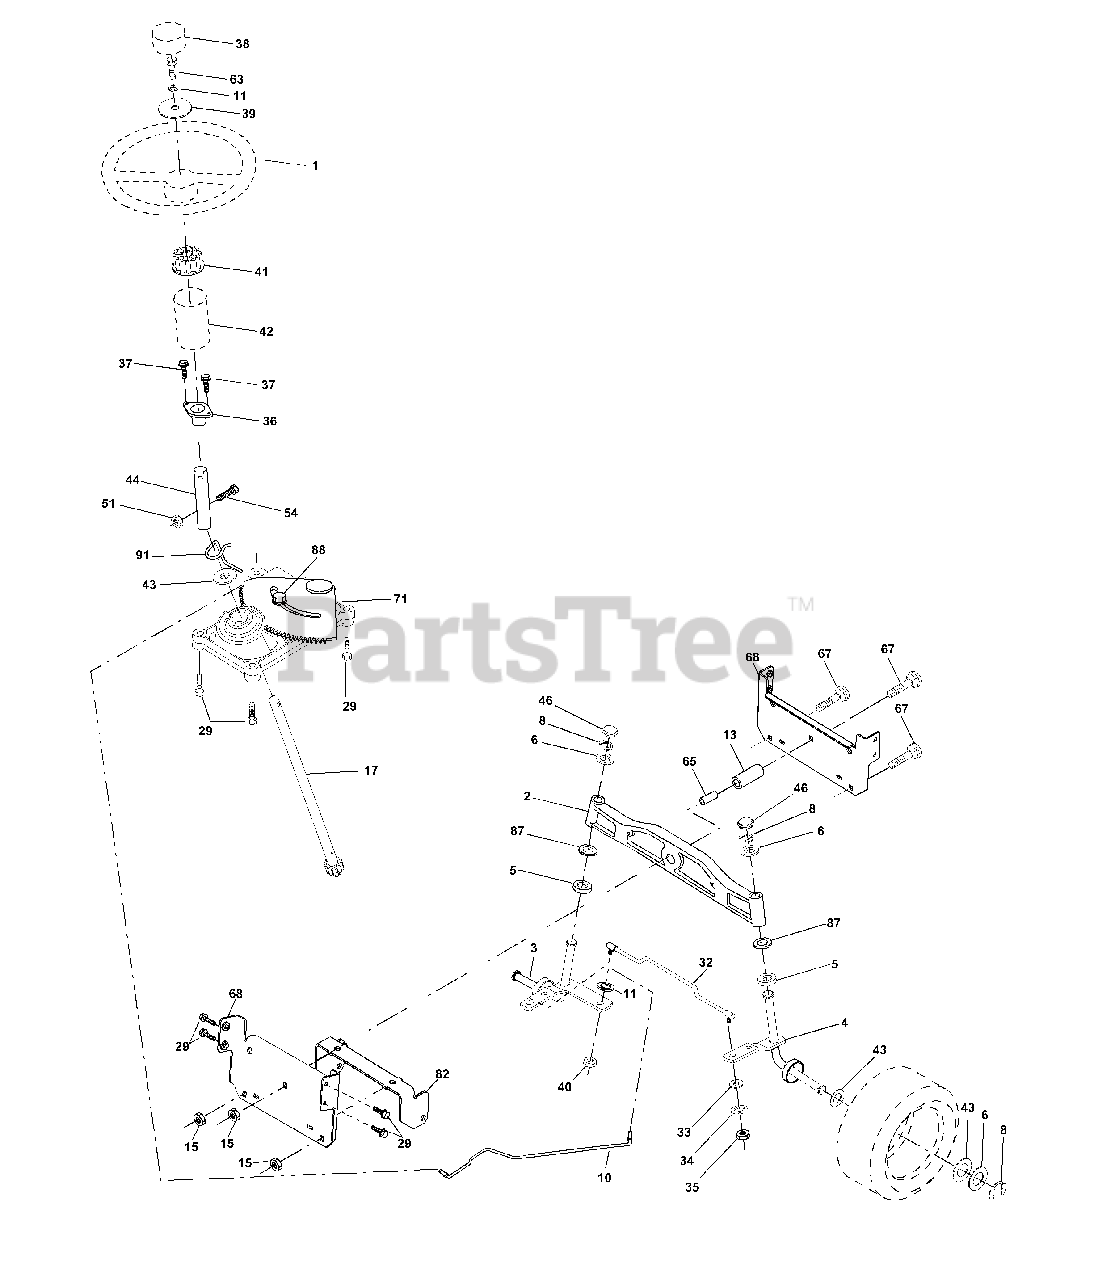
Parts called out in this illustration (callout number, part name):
1	Wheel Steering
2	Axle Asm Cast Iron LT
3	Spindle Asm LH
4	Spindle Asm RH
5	Bearing Race Thrust Harden
6	Washer 25/32 X 1-5/8 X 16 Ga
8	Ring Klip #t5304-75
10	Link Drag
11	Washer Lock Hvy Hlcl Spr 3/8
13	Spacer Brg. Axle Front
15	Nut Hex Flange Lock
17	Shaft Asm Steering
29	Screw 3/8-16x.75
32	Rod Tie
33	Washer 11/32 x 3/4 x 16 Ga.
34	Washer Lock Hvy Hlcl Spr 5/16
35	Crownlock Nut 5/16-24
36	Bushing Strg
37	Screw
38	Insert Cap Strg Wh Au
39	Washer 13/32 X 2-3/8 X 12 Ga
40	Lock nut
41	Adaptor Wheel Strg
42	Boot Steering Dash
43	Washer 25/32 X 1 1/4 X 16 Ga
44	Extension Steering Shaft LR/LT
46	Cap Spindle Fr Top Blk
51	Nut Lock Hex w/Ins 5/16-18
54	Bolt Fin Hex 5/16-18 Unc x 1-1/4
63	Bolt Fin Hex 3/8-16unc x 1 Gr. 5
65	Brace Axle
67	Bolt Rdhd Sq 3/8-16 Unc x 2-1/4
68	Axle, Brace
71	Steering Asm.
82	Bracket Susp. Chassis Front
87	Washer Flat .781 x 1-1/2 x .14
88	Bolt Shoulder 7/16-20 Unc
91	Clip Steering
